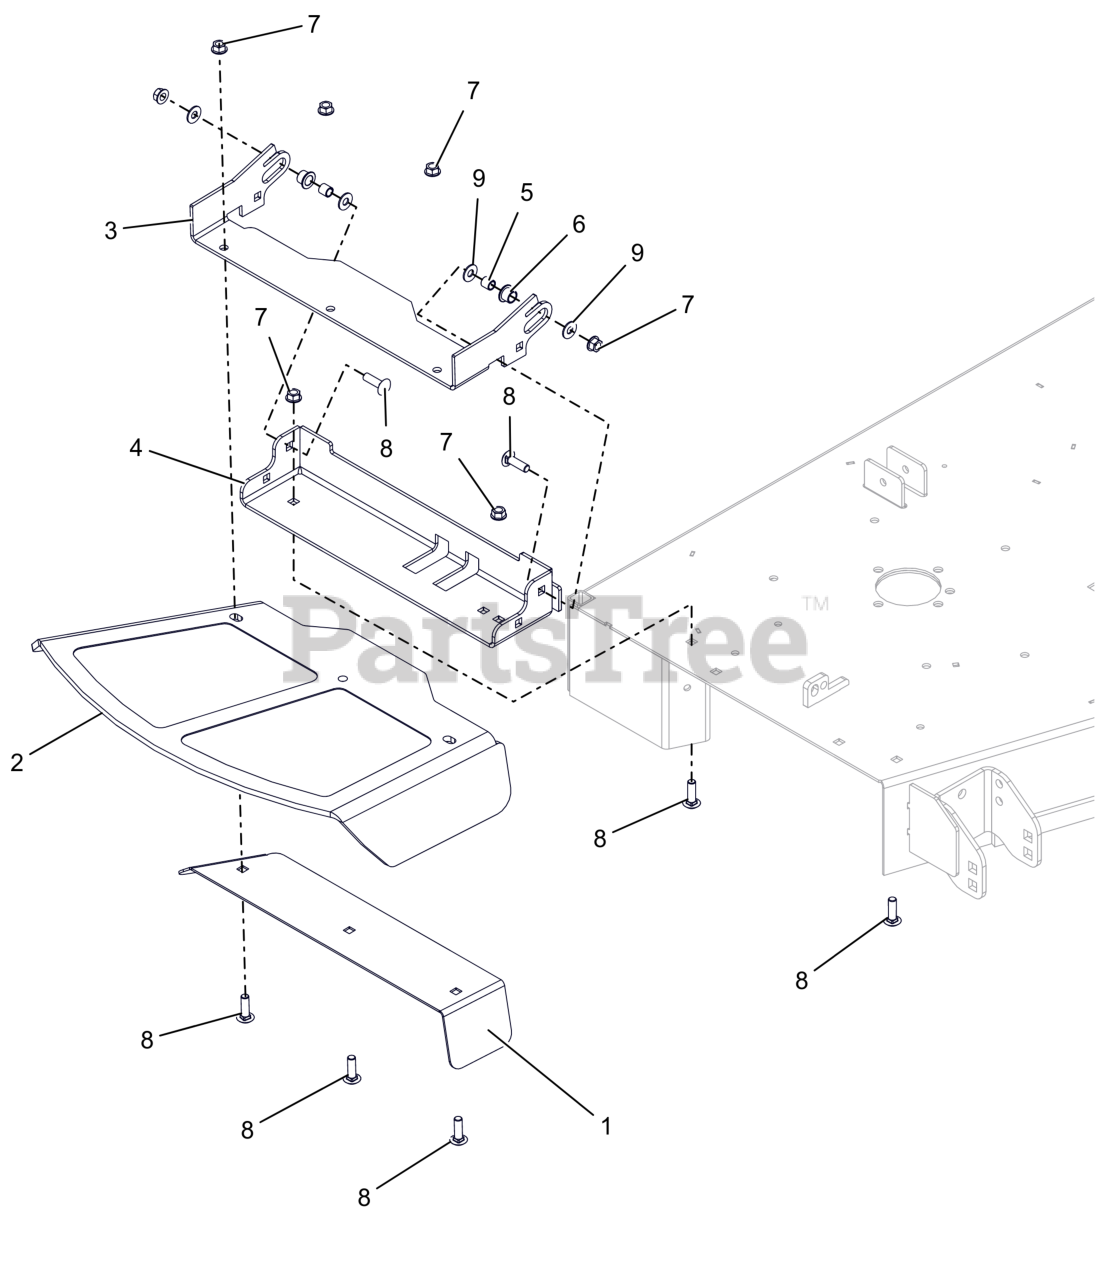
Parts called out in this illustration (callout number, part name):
1	PLT, DISCH. CHUTE CLMP-CE
2	CHUTE, FORMED RUBBER DISCHARGE
3	BRKT, CHUTE MOUNT (ORANGE)
4	BASE, DISCHARGE CHUTE MTG BRKT (ORANGE)
5	SPCR, .385X.500X.350
6	BSHG, FLANGED .50X.625X.50X.062
7	NUT-LK-CTR-FLG .375-16 GF ZCC
8	BLT,RHSSN .38-16X1.25 G5 ZCC
9	WSHR, HDND .375X.875X.064 ZCC
